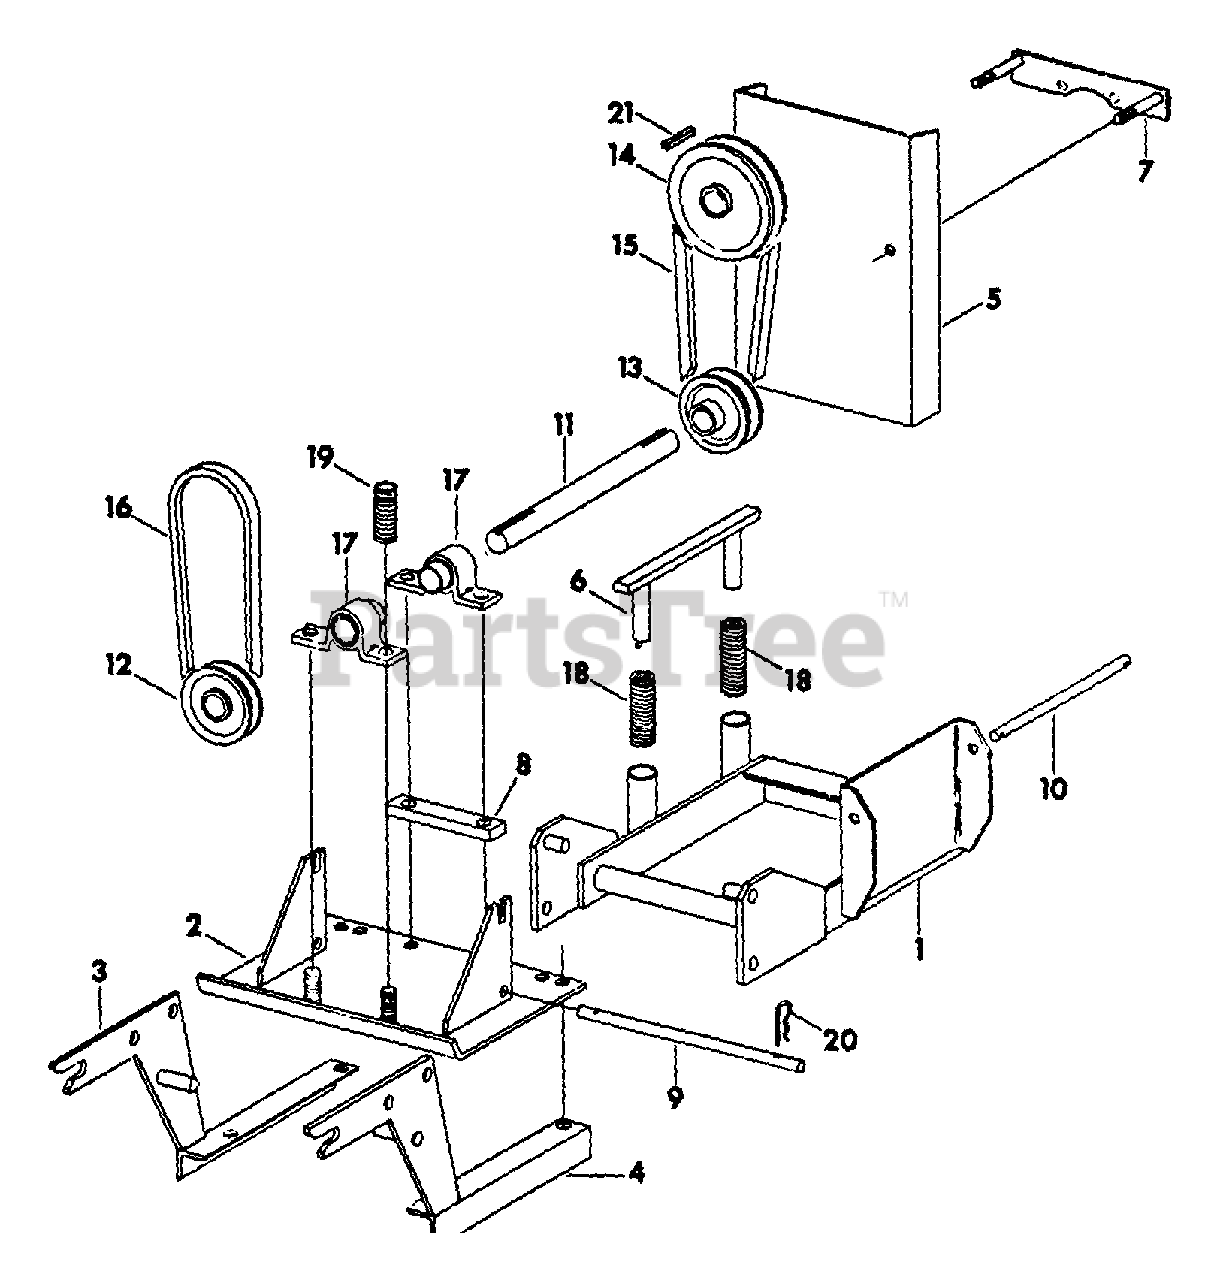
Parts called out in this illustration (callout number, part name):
1	FRAME
2	PLATE BRG
3	BRACKET, MOUNTING LH
4	BRACKET, MOUNTING RH
5	SHIELD
6	SUPPORT, BELT TENSIONING
7	BRACKET, SHIELD
8	SPACER
9	PIN, FRAME MOUNTING
10	PIN, SHREDDER MOUNTING
11	SHAFT, DRIVE
13	PULLEY, 4 IN. DIAMETER
14	PULLEY
15	V-BELT, 1/2 TOP WIDTH X 42 IN. OUTSIDE CIRCUMFERENCE
16	V-BELT, 1/2 TOP WIDTH X 30 IN. OUTSIDE CIRCUMFERENCE
17	BEARING, PILLOW BLOCK BALL
18	SPRING
19	SPRING
20	PIN, QUICK ATTACHABLE
21	KEY. 1/4 X 1 SQ PARALLEL
192450	SCREW, 5/16-18 X 5/16 ZND HEX-SOC-HD CUP-PT SET
